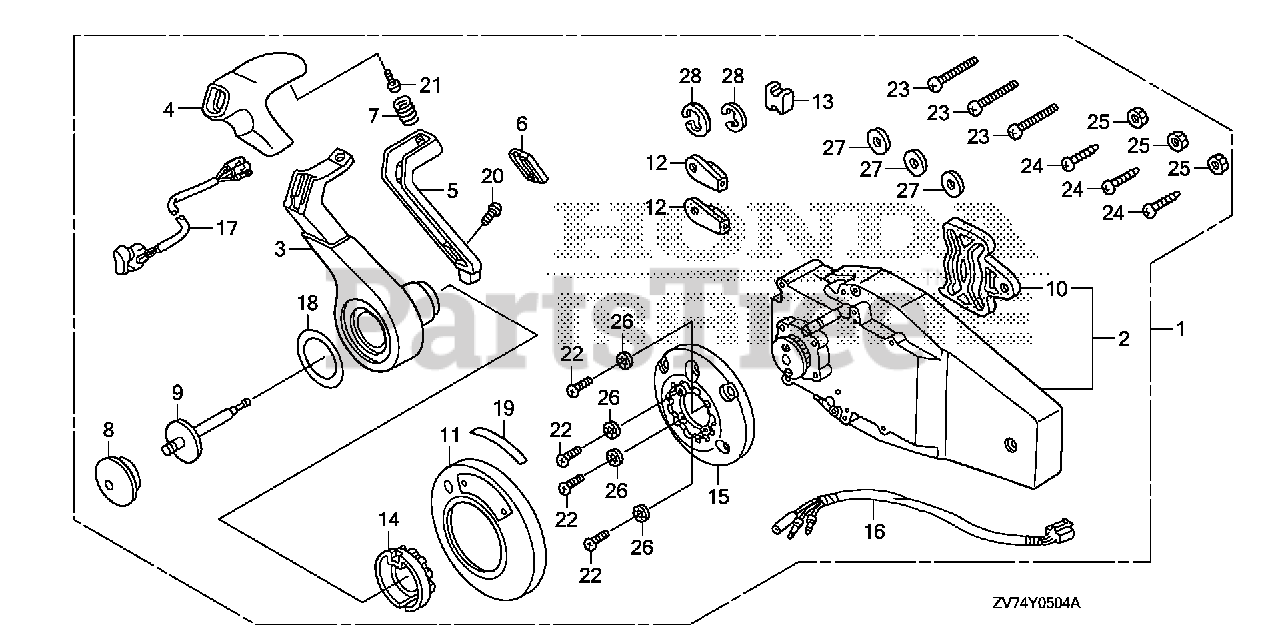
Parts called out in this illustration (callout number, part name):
1	BOX KIT, REMOTE CONTROL (FLUSH MOUNT)(R)
2	HOUSING ASSY., R. (INNER) (FLUSH MOUNT)
3	HANDLE, REMOTE CONTROL
4	COVER, GRIP
5	ARM, NEUTRAL LOCK
6	COVER, LOCK ARM
7	SPRING, NEUTRAL LOCK ARM
8	BUTTON, THROTTLE
9	SHAFT, THROTTLE BUTTON
10	PLATE, DWELL
11	COVER ASSY.
12	TERMINAL, CABLE
13	SPACER, CABLE CLAMP
14	HOLDER, NEUTRAL LOCK
15	BASE
16	SUB-HARNESS ASSY., POWER TRIM-TILT (C)
17	SWITCH ASSY., POWER TRIM-TILT (C)
18	MARK, HANDLE FLUSH MOUNT
19	MARK, FLUSH MOUNT
20	SCREW, TRUSS (4X12)
21	SCREW, PAN (5X16)
21	SCREW, PAN (5X10)
22	SCREW, PAN (5X30)
23	SCREW, PAN (6X35)
24	SCREW, TAPPING (6X30)
25	NUT, HEX. (6MM)
26	WASHER, LOCK (5MM)
27	WASHER, PLAIN (6MM)
28	E-RING (6MM)
